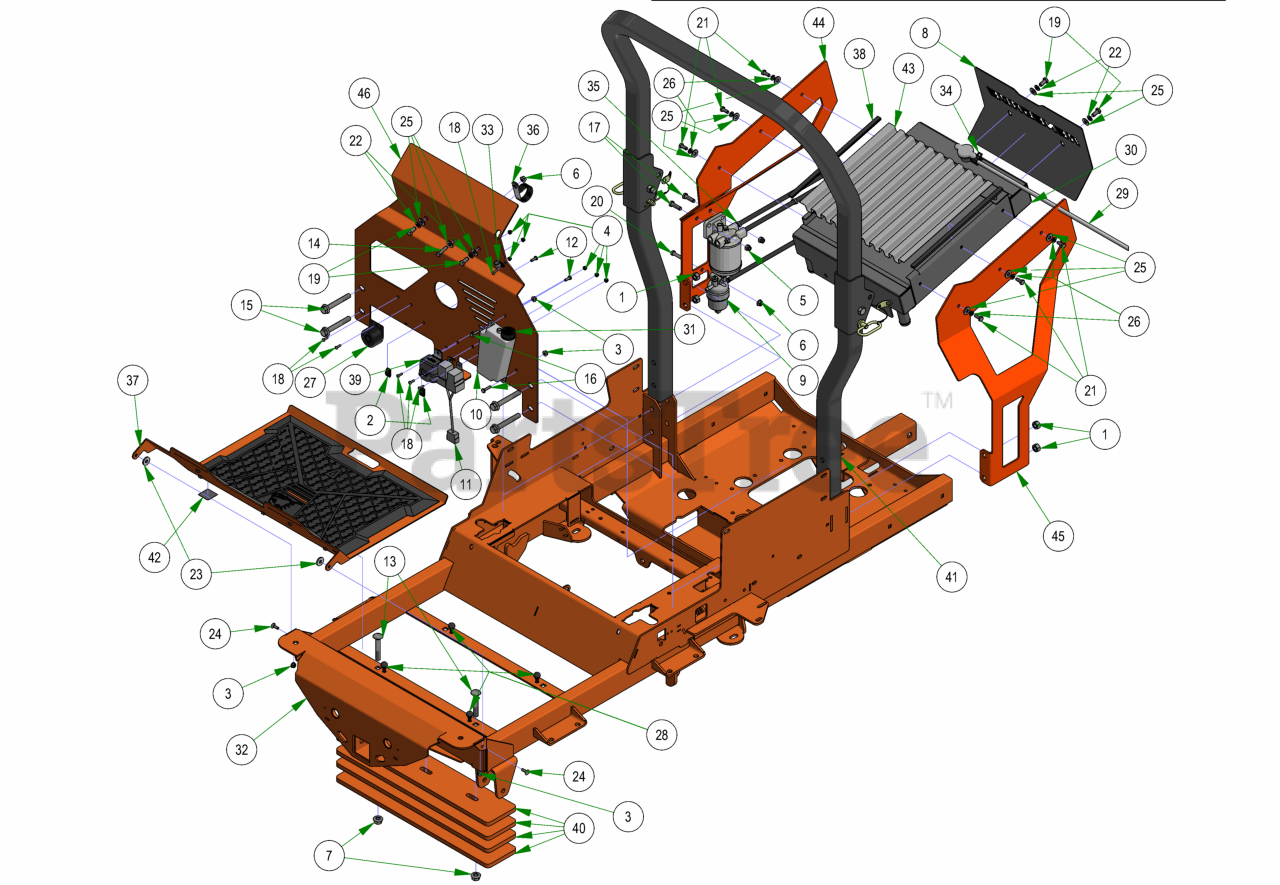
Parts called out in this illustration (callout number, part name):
1	1/2-13 HEX 2-WAY REVERSIBLE CENTER LOCKNUT Grade B ZINC
2	1/4-20 Cage Nut
3	1/4-20 NYL INSERT FLANGE LOCKNUT ZINC
4	10-24 NYLON INSERT LOCKNUT ZINC
5	3/8-16 NYLON INSERT LOCKNUT ZINC
6	5/16-18 NYLON INSERT FLANGE LOCKNUT ZINC
7	1/2-13 NYLON INSERT FLANGE LOCKNUT ZINC
8	2019 Diesel Upper Rear Cover - Black
9	24.7HP Perkins Engine, 403J-11
10	overflow Reservoir- 27Kaw & 28/35Hp Diesel
11	Diesel Relay Auto Shut Down Assembly
12	M6-1.0 X 16MM DIN 933 HEX TAP BOLT (CL 8.8) ZINC
13	1/2-13 x 3 Carriage Bolt Grade 5
14	5/16-18 X 1-1/4 HEX C/S (GR.5) ZC
15	1/2-13 X 3-1/2 HEX FLANGE BOLT (GR.8) ZINC
16	1/4-20 X 1 HEX CAP SCREW (GR.5) ZINC
17	3/8-16 X 1-1/4 HEX CAP SCREW (GR.5) ZINC
18	10-24 X 5/8 BUTTON SOCKET CAP SCREW 18-8 STAINLESS STEEL
19	3/8-16 X 3/4 HEX CAP SCREW (GR.5) ZINC
20	5/16-18 X 2-1/2 HEX CAP SCREW (GR.5) ZINC
21	5/16-18 X 3/4 HEX CAP SCREW (GR.5) ZINC
22	3/8 SPLIT LOCKWASHER ZINC
23	.360 ID X .983 OD X .120 THICK FLAT WASHER NYLON
24	1/4-20 X 3/4 CARRIAGE BOLT (GR.5) ZINC
25	5/16 USS FLAT WASHER (7/8 OD) ZINC
26	5/16 SPLIT LOCKWASHER ZINC
27	Heat Warning Piezo Buzzer
28	2023 Floor Board Rubber Bumper
29	2022 Renegade Diesel Fuel Line Assembly
30	2019 Diesel Radiator Kit
31	Reservoir Tank Cap-Overflow
32	2022 Horizontal Diesel Frame
33	3/8 Cable Clamp-Black Nylon
34	5/8 Hose Clamp
35	2 EAR CLAMP 12.5mm-15mm
36	Diesel Clamp 1 3/4" Vinyl
37	2024 R-Series Floorboard Assembly
38	Rubber Trim
39	2022 Renegade Diesel Wiring Harness
40	2019 Outlaw Counter Weight
41	2019 2X2 Folding ROPS
42	Patent Decal (Anti-Wobble)
43	Radiator Screen Diesel
44	2019 Diesel Radiator Mount - Right
45	2019 Diesel Radiator Mount - Left
46	2022 Diesel Radiator Mount
